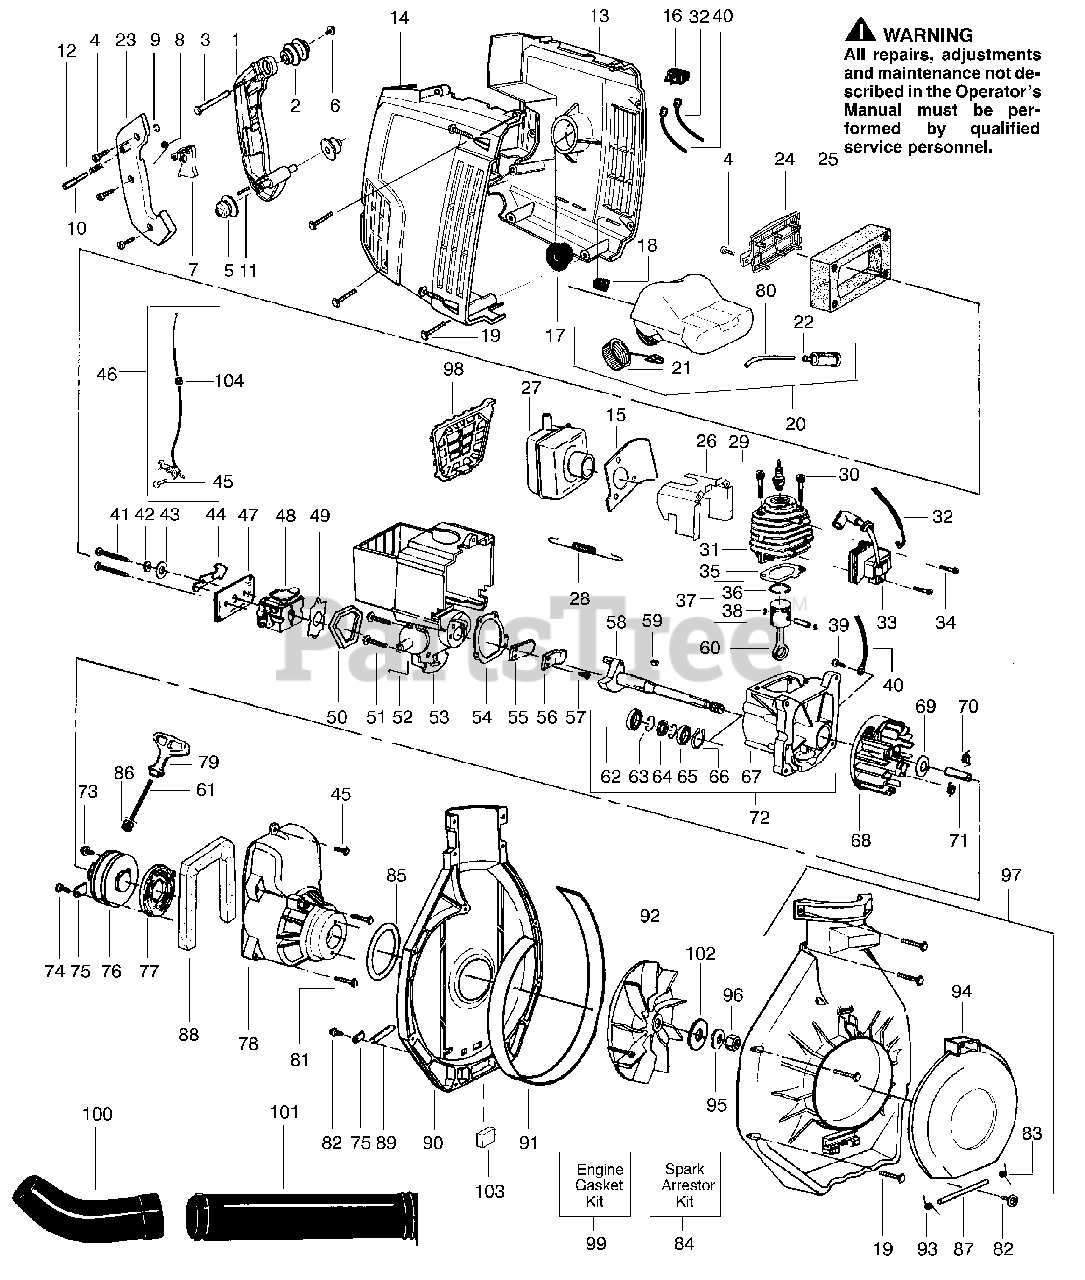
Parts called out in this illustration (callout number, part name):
1	Handle Kit
2	Isolator
3	Spacer-Isolator
5	Isolator-Handle (Rear)
8	Spring-Lever Return
9	"C" Clip-Throttle Lock
10	Throttle Lock Button
11	Pin-Handle
12	Spring-Throttle
13	Shroud-Left
14	Shroud-Right
15	Heat Shield Air Dam
16	Switch Kit
17	Isolator-Engine Mount
18	Isolator Tank
20	Fuel Tank Ass'y.
21	Fuel Cap Ass'y. w/retainer
22	Fuel Pick-up Ass'y.
23	Handle Cover Ass'y.
24	Cover-Filter
25	Air Filter (Foam)
26	Air Baffle
27	Muffler Kit
28	Spring-Muffler
29	Spark Plug (RCJ-8Y)
31	Cylinder Kit
32	Lead Wire (Switch)
33	Ignition Module
35	Gasket-Cylinder
36	Piston Ring
37	Piston Kit
38	Retainer
40	Ground Wire (Switch)
43	Spacer-Choke
44	Choke Shutter
46	Cable Assembly
47	Plate-Air Filter Mtg.
48	Carburetor Ass'y. Kit
49	Gasket-Carb
50	Seal-Foam/Reed Block
52	Ground Wire (Static)
53	Reed Block/Heat Shield
54	Gasket-Reed Block/C'case
55	Reed Valve
56	Reed Stop
58	Crankshaft Ass'y.
59	Flywheel Key
60	Connecting Rod Ass'y.
61	Rope Kit
62	Inner Bearing
63	Retaining Ring
64	Crankshaft Seal
65	Outer Bearing
66	Retaining Ring (Shaft)
67	Crankcase Ass'y.
68	Flywheel Ass'y.
69	Washer
70	Spring-Starter Dog
71	Spacer-Flywheel
72	Crankcase/Crankshaft Assy.
75	Retainer
76	Starter Pulley Kit
77	Starter Spring
78	Fan Housing Kit
79	Starter Handle
80	Line Kit
83	Spring-Torsion (Left)
84	Spark Arrestor Kit
85	"O" Ring-Seal
86	Eyelet-Flange
87	Pin-Pivot
88	Sponge-Air Dam
89	Tube-Rope Retainer
90	Blower Housing (Upper)
91	Band-Blower Hsg.
92	Impeller Ass'y.
93	Spring-Torsion (Right)
94	Inlet Door
95	Washer-Conical
97	Blower Housing (Lower)
98	Muffler Guard Kit
99	Gasket Kit
100	Nozzle-Concentrator
101	Blower Tube (Upper)
102	Washer-Impeller
103	Seal Foam
